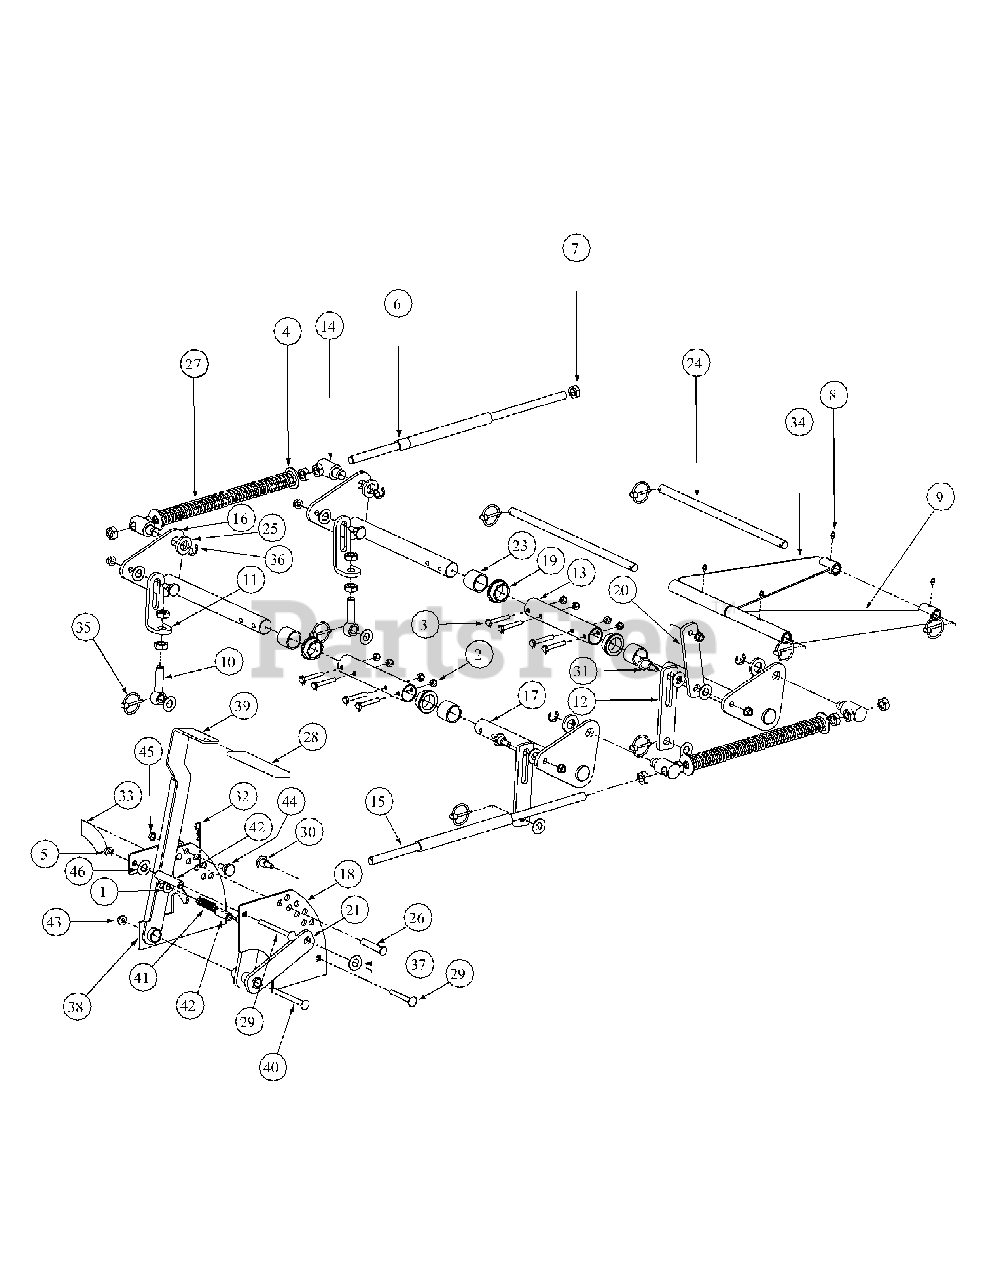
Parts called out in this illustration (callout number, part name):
1	Flat Washer, SAE, 3/4
2	Nut, 5/16-18, Nylock
3	HHCS, 5/16-18 x 2
4	Flat Washer, 5/8, USS
5	Hex Nut, 3/8-16 Flange Lock
6	Hose, 5/8" PVC, Clear Reinforced (in ft.)
7	Jam Nut, 5/8-11
8	Grease Fitting, 1/4-28, x 3/16
9	Brace Assembly, Right Hand Bearing Lift
9	Bearings
10	Eye Bolt, 5/8 ID
11	Mounting Link, 5/8 ID Eye Bolt
12	Deck Link
13	Holder, Shaft Lift
14	Ferrule Lift
15	Rod, Connector Lift
16	Weldment, Bellcrank Lift Right Hand
17	Weldment, Bellcrank Lift Left Hand
18	Plate index Lift
19	Bearing Flange, Hex, 1.25
20	Link, Lift, Index To Bellcrank
21	Weldment, Lift Handle
23	Spacer Lift Frame
24	Rod Mount Front Lift Link
25	Spacer, .812 ID x .268 Long
26	Clevis Pin, .500 Dia. x 2.625 Long
27	Spring, Compression, Lift
28	Grip, Lift Handle
29	Carriage Bolt, 3/8-16, 2.75
30	Shoulder Screw, .625 OD x .437 Long
31	Shoulder Screw,.625 OD x .830 Long
32	Cotter Pin, .148 x 3.00
33	Decal, Height Indicator
34	Brace Assembly, Left Hand Bearing Lift
34	Bearings
35	Linch Pin, 3/16 Dia
36	Clip E, 3/4 Dia
37	Flat Washer, 5/8 Nylon
38	Weldment, Plate, Index, Lift
39	Lift, Handle Assembly
40	Screw, Hex Cap, 3/8-16 x 3.75
41	Spring, Lift Handle
42	Spacer, .39 ID x .63 OD x 1.442
43	Nut, Lock, Nylon Insert, 3/8-16
44	Shoulder Screw, 5/8 OD x 0.264
45	Nut, Nylon Lock, 1/2-13
46	Idler Washer
